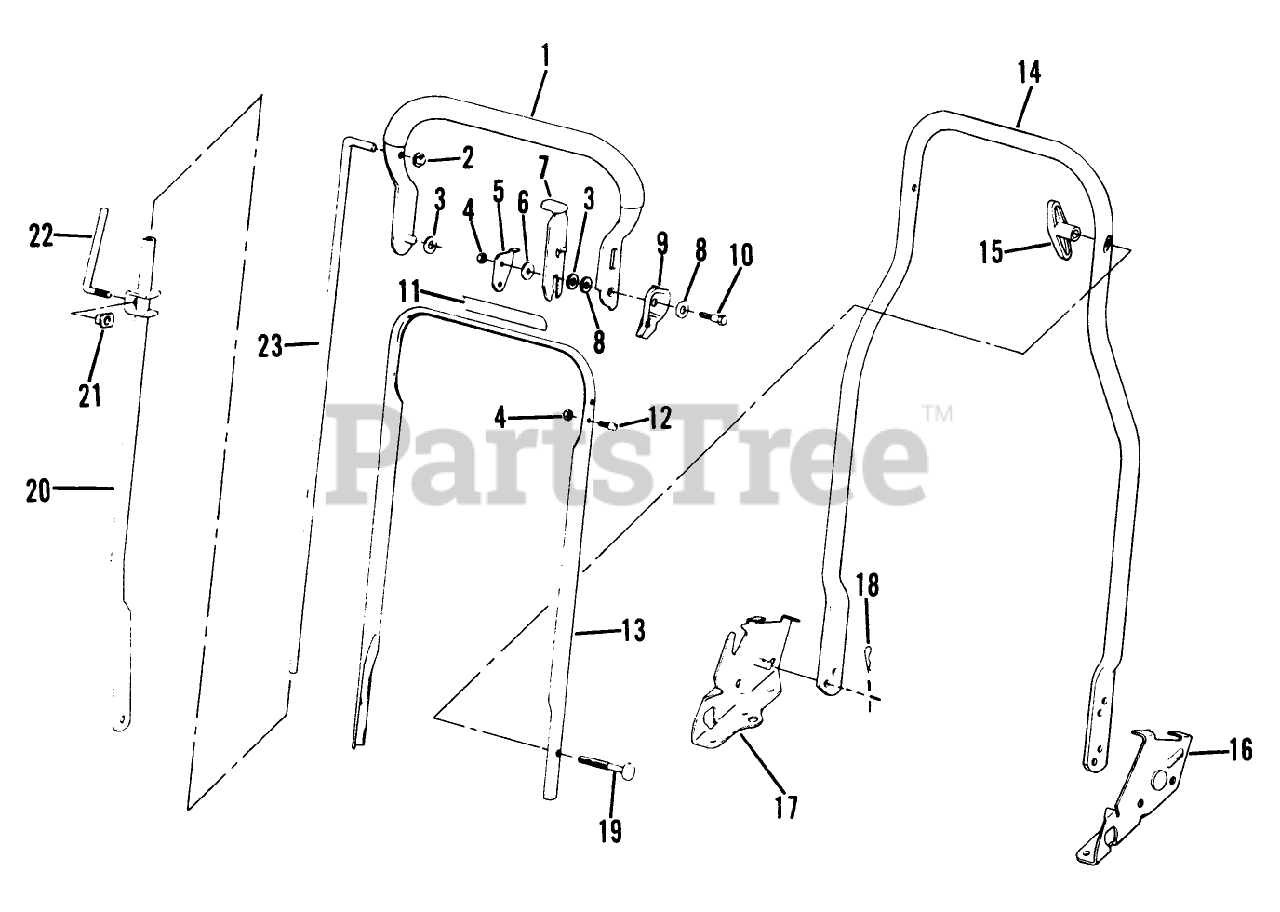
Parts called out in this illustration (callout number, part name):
3	WASHER M
4	LOCKNUT E
5	HANDLE STOP
6	WASHER
8	Washer
10	BOLT PIONEER
11	DISCOUNTED
12	SCREW-HANDLE STOP
13	HANDLE
14	Handle Section-Bottom
15	NUT-WING
17	HANDLE BRACKET
18	HAIR PIN
23	ROD CONTROL
